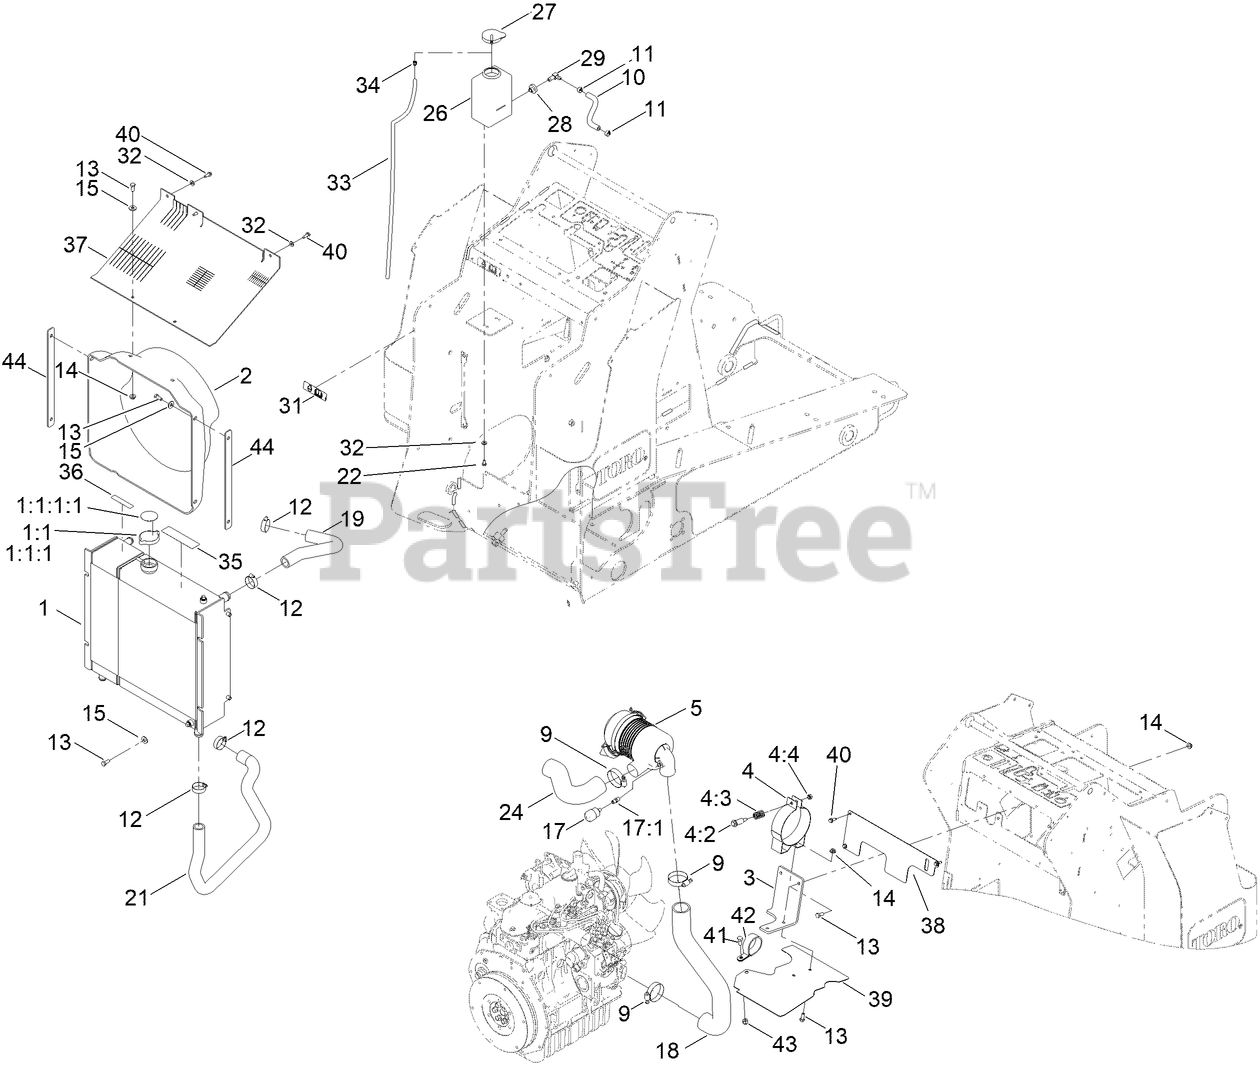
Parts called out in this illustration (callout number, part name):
1	COOLING ASM
1:1	RADIATOR CAP ASM
1:1:1	CAP-RADIATOR
1:1:1:1	DECAL-DANGER
2	SHROUD-FAN
4	AIR CLEANER MOUNTING BAND ASM
4:3	SPRING
4:4	NUT
5	AIR CLEANER ASM
9	CLAMP-HOSE
10	HOSE-FUEL
11	CLAMP-HOSE
12	CLAMP-HOSE
13	SCREW-HH
14	NUT-HF
15	WASHER-FLAT
17	INDICATOR
17:1	ADAPTER-INDICATOR
18	HOSE-INTAKE, ENGINE
19	HOSE-RADIATOR
21	HOSE-RADIATOR, LOWER
22	SCREW-HH
24	HOSE-AIR, INLET
26	TANK-OVERFLOW
27	CAP-TANK, OVERFLOW
28	BUSHING
29	FITTING-ELBOW, 90 DEG
31	DECAL-RADIATOR FILL
32	WASHER-FLAT
33	HOSE-LP
34	CLAMP-HOSE
35	DECAL-DANGER
36	DECAL-WARNING, FAN
37	GUARD-AIR
38	COVER-AIR
39	BAFFLE-HEAT
40	SCREW-HWH, THREAD ROLL
41	SCREW-HH
42	CLAMP-R
43	NUT-LOCK, NI
44	PLATE-SHIM
